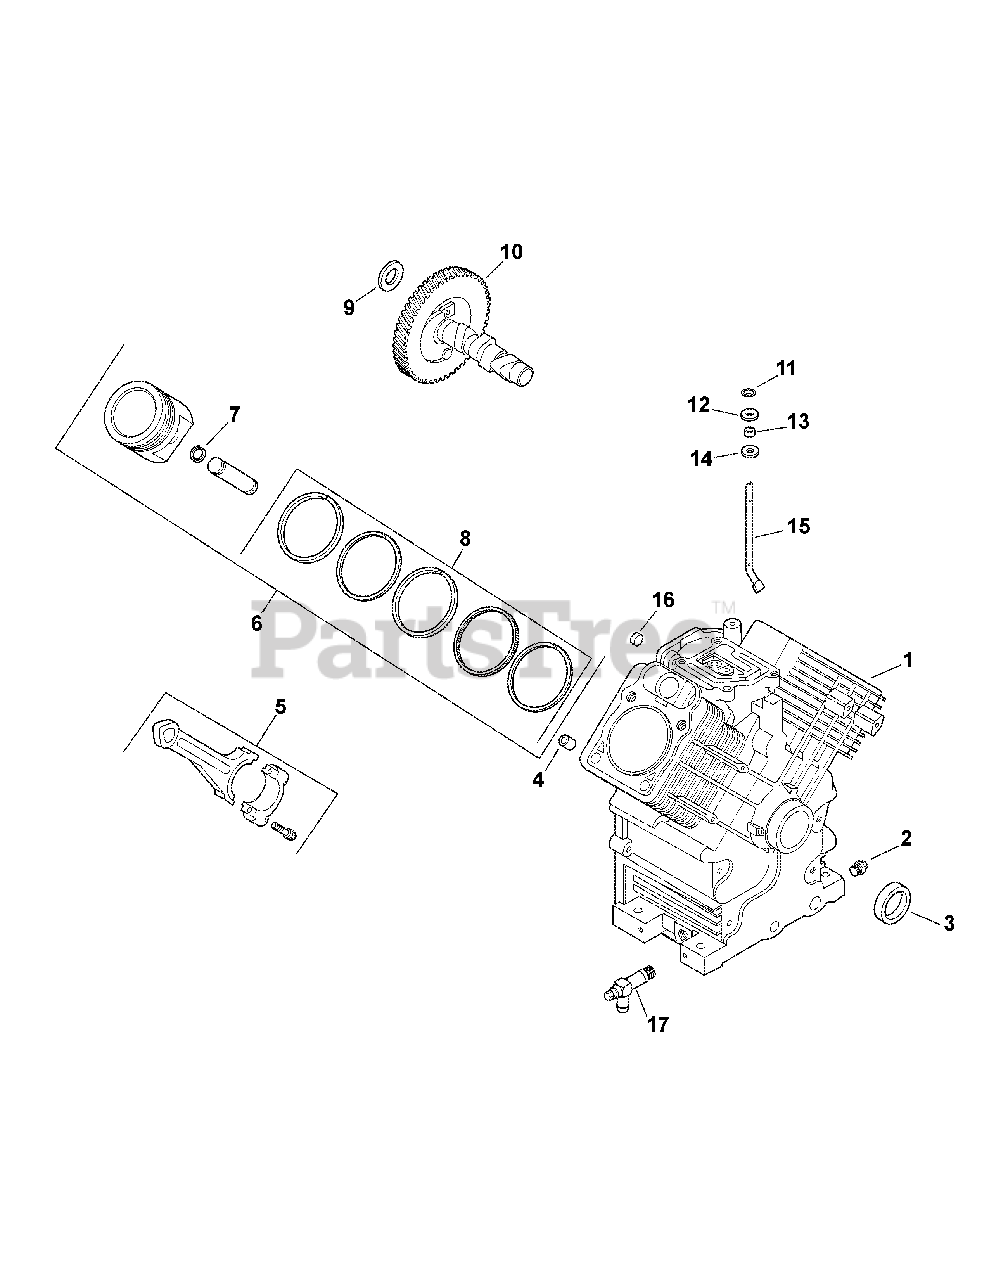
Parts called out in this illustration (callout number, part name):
1	Crankcase
2	Plug, sq. head 3/8"
3	Seal, front oil
4	Pin, loYanmaring
5	Connecting Rod (Std.)
5	Connecting Rod (.25)
6	Piston w/Ring Set (Std.)
6	Piston w/Ring Set (.08)
6	Piston w/Ring Set (.25)
6	Piston w/Ring Set (.50)
7	Retainer, piston pin
8	Ring Set (Std. & .08)
8	Ring Set (.25)
8	Ring Set (.50)
9	Shim, camshaft (A.R.) red
9	Shim, camshaft (A.R.) black
9	Shim, camshaft (A.R.) white
9	Shim, camshaft (A.R.) blue
9	Shim, camshaft - yellow
9	Shim, camshaft (A.R.) green
9	Shim, camshaft (A.R.) gray
10	Camshaft
11	Retainer, ring
12	Washer, plain 9 mm
13	Seal, governor cross shaft
14	Washer, plain 1/4"
15	Shaft, governor cross
17	Valve, oil drain
